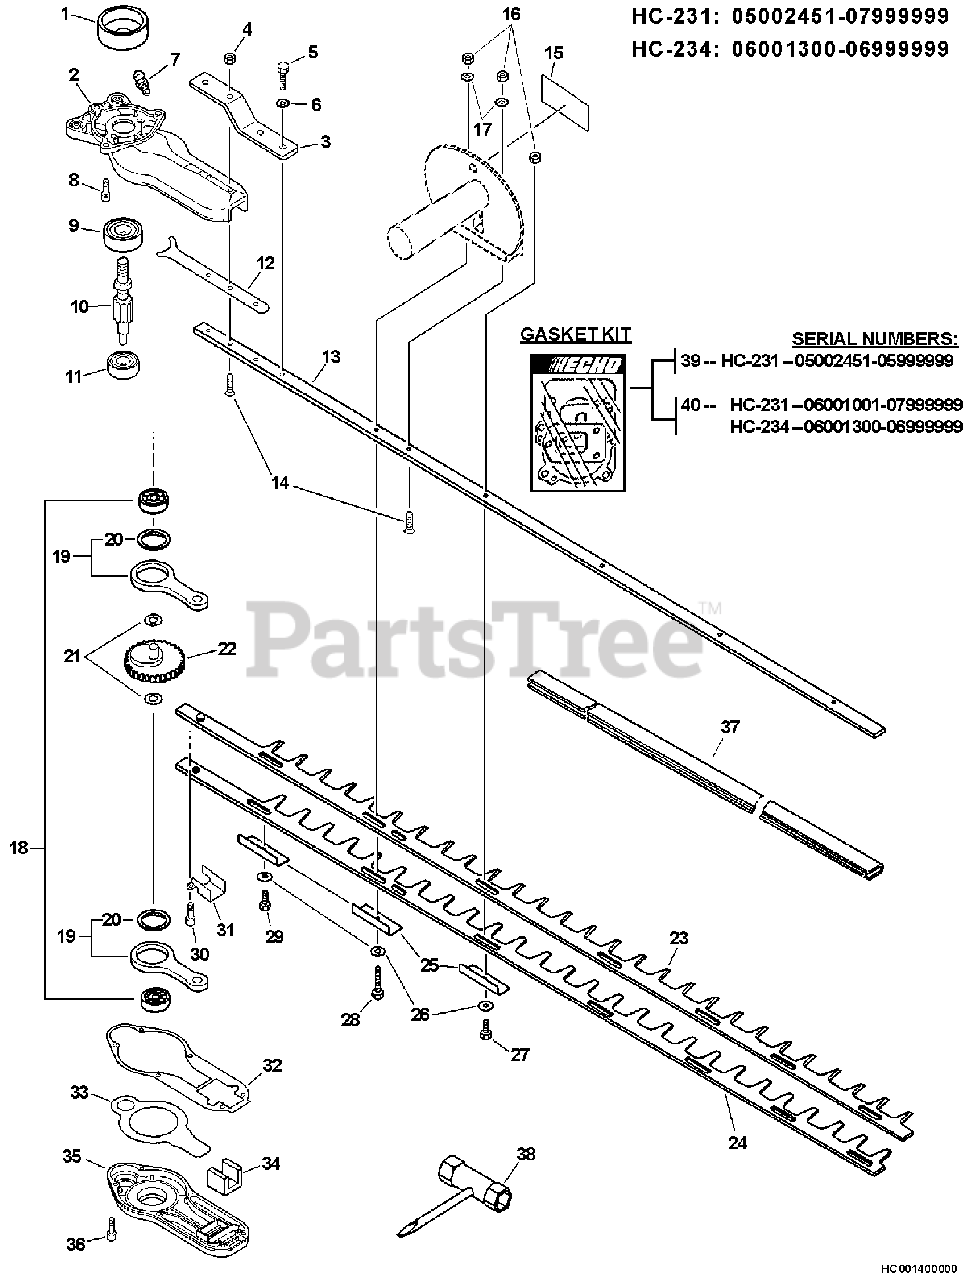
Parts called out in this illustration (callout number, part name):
1	DRUM, CLUTCH
2	CASE, GEAR - UPPER
3	BRACKET, BLADE
4	NUT, FLANGE M6
5	SCREW - 6×12
7	FITTING, GREASE
8	BOLT 6×18
9	BEARING, BALL 6200
10	GEAR, SPUR
11	BEARING, BALL 608ZZ
12	PLATE, EYE
13	SUPPORT, BLADE
14	BOLT 6×30
15	LABEL, CAUTION
17	WASHER 6.5×13×1
18	BEARING, BALL 6200
19	ROD, CONNECTING
20	BEARING, NEEDLE 30
21	WASHER, THRUST 10
22	GEAR, SPUR
23	BLADE - UPPER -- 40"
24	BLADE, TRIMMER - 40" -- LOWER
25	GUIDE, BLADE
27	BOLT 6×22
28	BOLT 6×40
29	BOLT 6×35
30	BOLT 4×16
31	GUIDE, BLADE
32	GASKET, GEAR CASE
33	PLATE, GEAR CASE
34	SEAL
35	CASE, GEAR - LOWER
36	BOLT 4×16
37	SCABBARD
38	T-WRENCH 13×19×180
39	GASKET KIT
40	GASKET KIT
